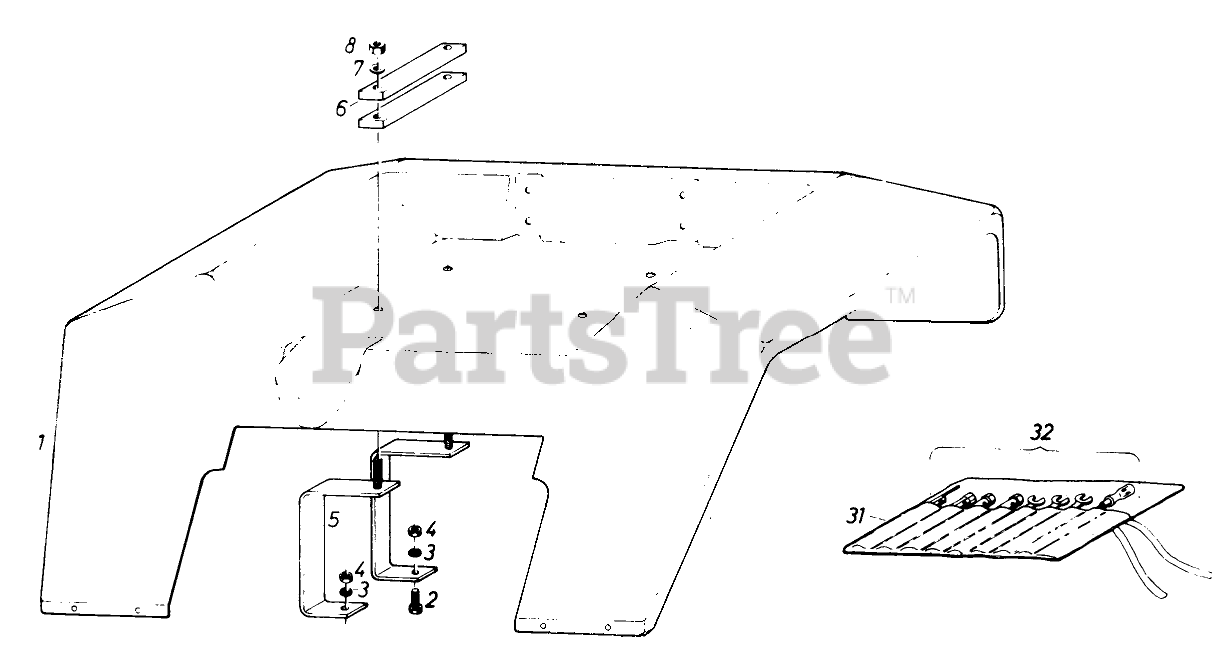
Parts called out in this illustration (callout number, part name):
1	Fender and Seat
3	Washer
5	Support Assy
7	Washer
31	Tool Kit Holder
32	Tool Set Cpl
